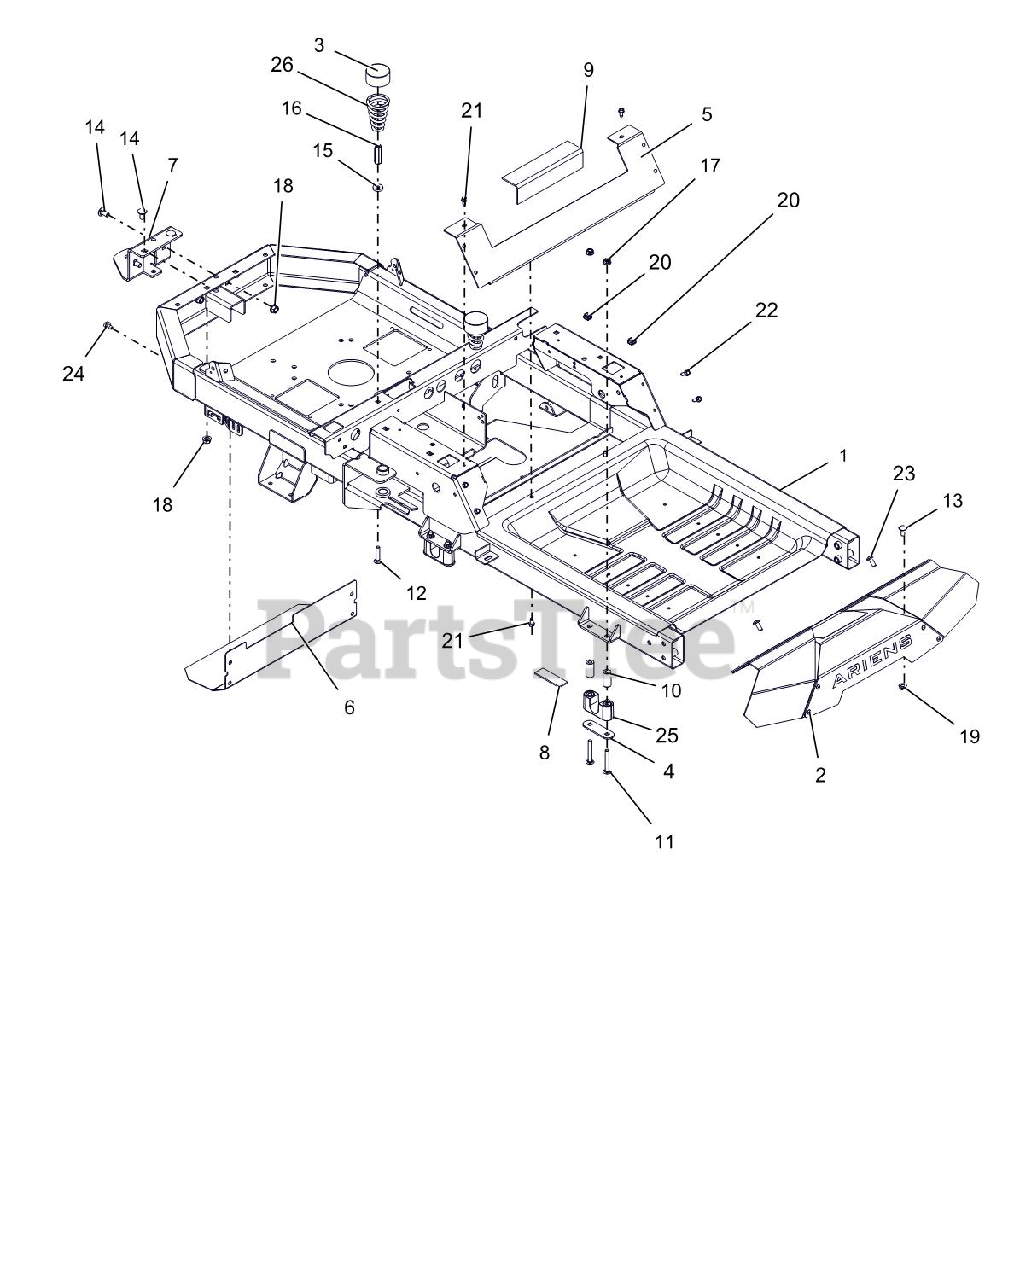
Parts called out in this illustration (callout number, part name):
1	KIT, IKON-X/XL FRAME (2016)
2	KIT, IKON FOOT REST W/DECAL
3	HUB CAP
4	PLATE, BEARING SUPPORT
5	PLATE, SEAT KICK
6	HEAT, SHIELD
7	BRKT, HITCH TONGUE
8	PAD,RBR 1.0"X3.0" W/ADHESIVE
9	PAD, RUBBER-TANK
10	SPACER, .323 X .698 X 1.441
11	BLT-RDHDSQSHNK .31-18X2.25 YWZ
12	@BLT-RDHDSQNK .31-18X1.50 G5YZ
13	@BLT-RDHDSQNK .31-18X.75 G5YZ
14	@BLT-RDHDSQNK .38-16X.75 G5YZ
15	WSHR-FL-STL .328X.87X.179 YWZC
16	NUT, COUPLING 5/16-18 X 1 3/4
17	@NUT-LK-CTR-FLG .31-18 YZ GR F
18	@NUT-LK-TOP-FLG .38-16 YWZC
19	@NUT-LK-TOP-FLG .31-18 YWZC
20	NUT RETNR .25-20
21	SCR-TAP .25-20X.50 HWH TR YWZ
22	SCR-TAP-PM .25-20X.75 TR YWZ
23	SCR-RDHDSKTAP .31-18 X .75
24	@SCR-TAP .31-18X.50 HWH TR YWZ
25	BSHG, DECK LIFT PIVOT
26	SPRING, SEAT
